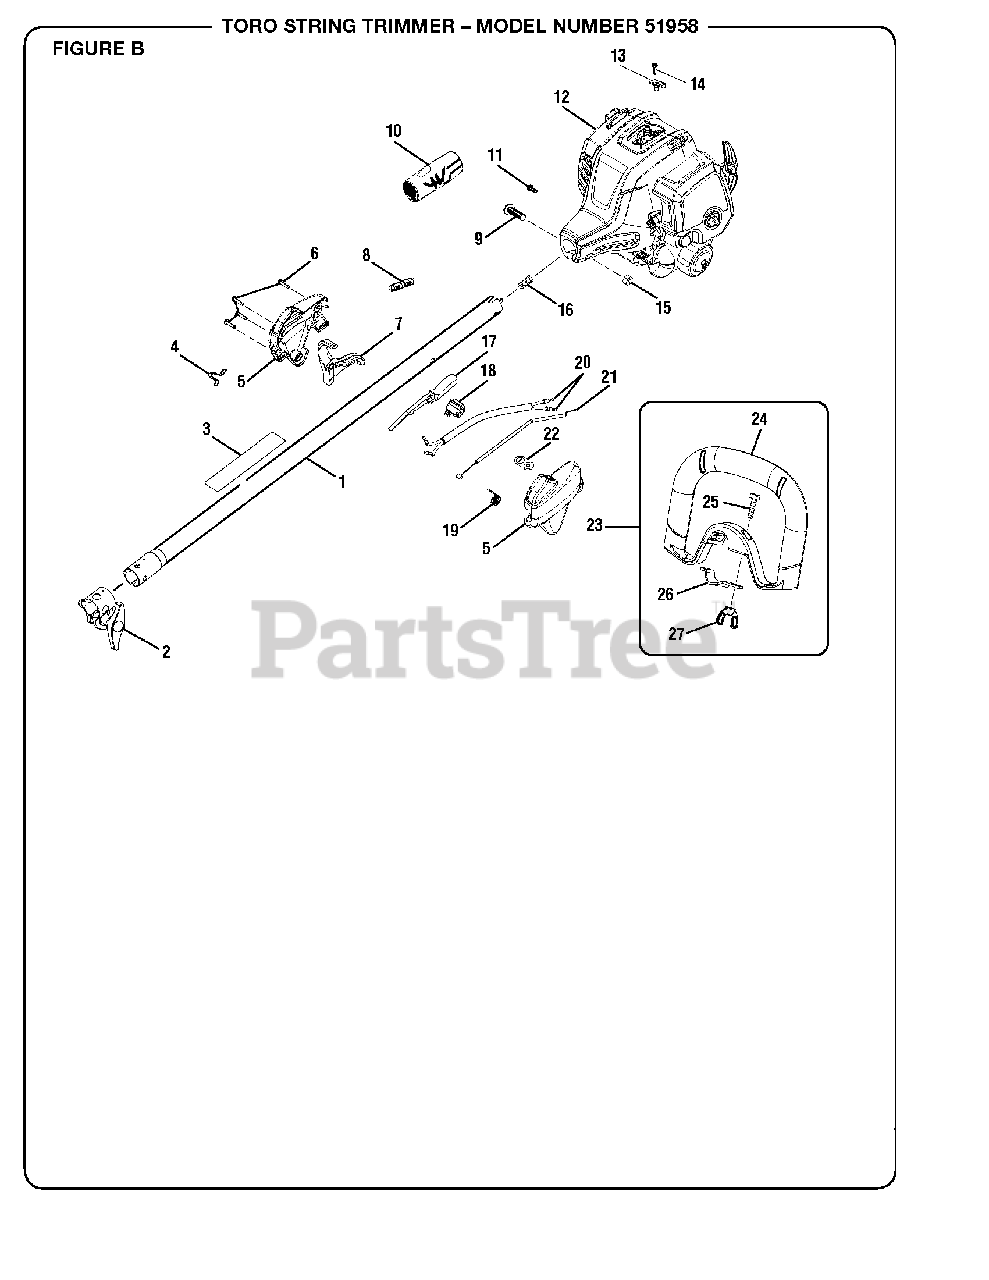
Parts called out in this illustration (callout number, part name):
1	Upper Boom Assembly
2	Boom Clamp Assembly
3	Warning Label
4	Shoulder Strap Clip
5	Control Handle Assembly
6	Screw (M4 x 20 mm, T20 Torx Hd.)
8	Corrugated Tube
9	Screw (M6 x 30 mm)
10	Rear Handle Grip
11	Screw (M4 x 8 mm, T20 Torx Hd.)
12	Powerhead Assembly
13	Throttle Cable Clamp
14	Screw (M4 x 16 mm)
15	Hex Nut (M6.3 x 1)
16	Compression Spring
17	Trigger Lock
18	On/Stop Switch
19	Throttle Cable Spring
20	Lead Assembly
21	Throttle Cable
22	On/Stop Label
23	Front Handle Assembly
24	Front Handle w/Grip
25	Screw (1/4-20 x 1 in., Sq. Hd.)
26	Front Handle Clamp
27	Wing Nut (1/4-20)
